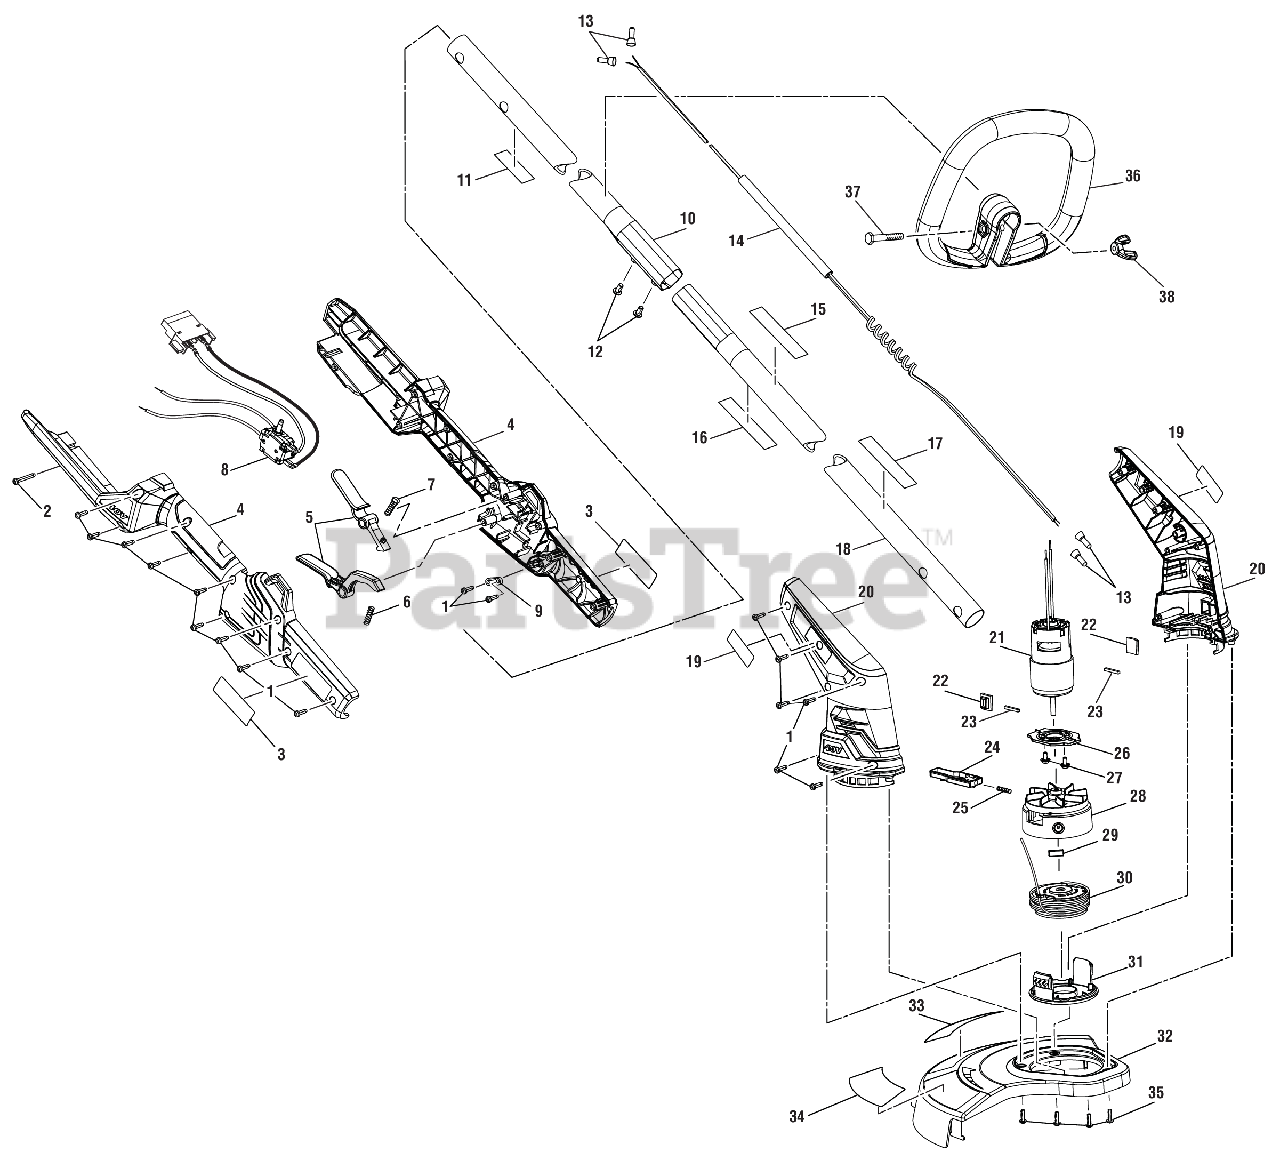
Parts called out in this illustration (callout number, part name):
1	Screw (M4 x 14 mm, T15 Torx Pan Hd.))
2	Screw (M4-18 x 30 mm, T15 Torx Soc. Hd.)
3	Logo Label
4	Handle Housing Assembly, ABS
5	Trigger Assembly, POM
6	Compression Spring (Trigger)
7	Compression Spring (Trigger)
8	Wiring Harness
9	Strain Relief Plate
10	Upper Tube w/ Labels, Low Carbon Steel
11	Label, Data
12	Screw w/Lock Washer (M5 x 8 mm, Pan Hd.)
13	Wire Connector (Closed End)
14	Spring Wire, 18 AWG 300V
15	Warning Icon Label
16	Warning Label (Upper End)
17	Label, Logo, Shaft
18	Lower Tube w/ Labels, Low Carbon Steel
19	Label, Logo, Motor Housing
20	Motor Housing Assembly, ABS
21	Motor, 40V 11500 RPM
22	Rubber Plate, EPDM
23	Rubber Plate (Motor Plate)
24	Slider Assembly
25	Compression Spring (Internal Tooth)
26	Mounting Plate, PA66
27	Screw w/Washer (M4 x 8 mm)
28	Spool Base w/Fan
29	BALANCE PLATE
30	Spool w/ Line Assembly
31	Spool Cap (AC14HCA)
32	Guard Assembly, PP
33	Adjustable Cutting Width Label
34	Auto-Feed Label
35	Screw (M4 x 12 mm, Pan Hd.)
36	Front Handle
37	Screw (1/4-20 x 40 mm, Cap Hex Hd.)
38	Wing Nut (1/4-20, Plastic)
